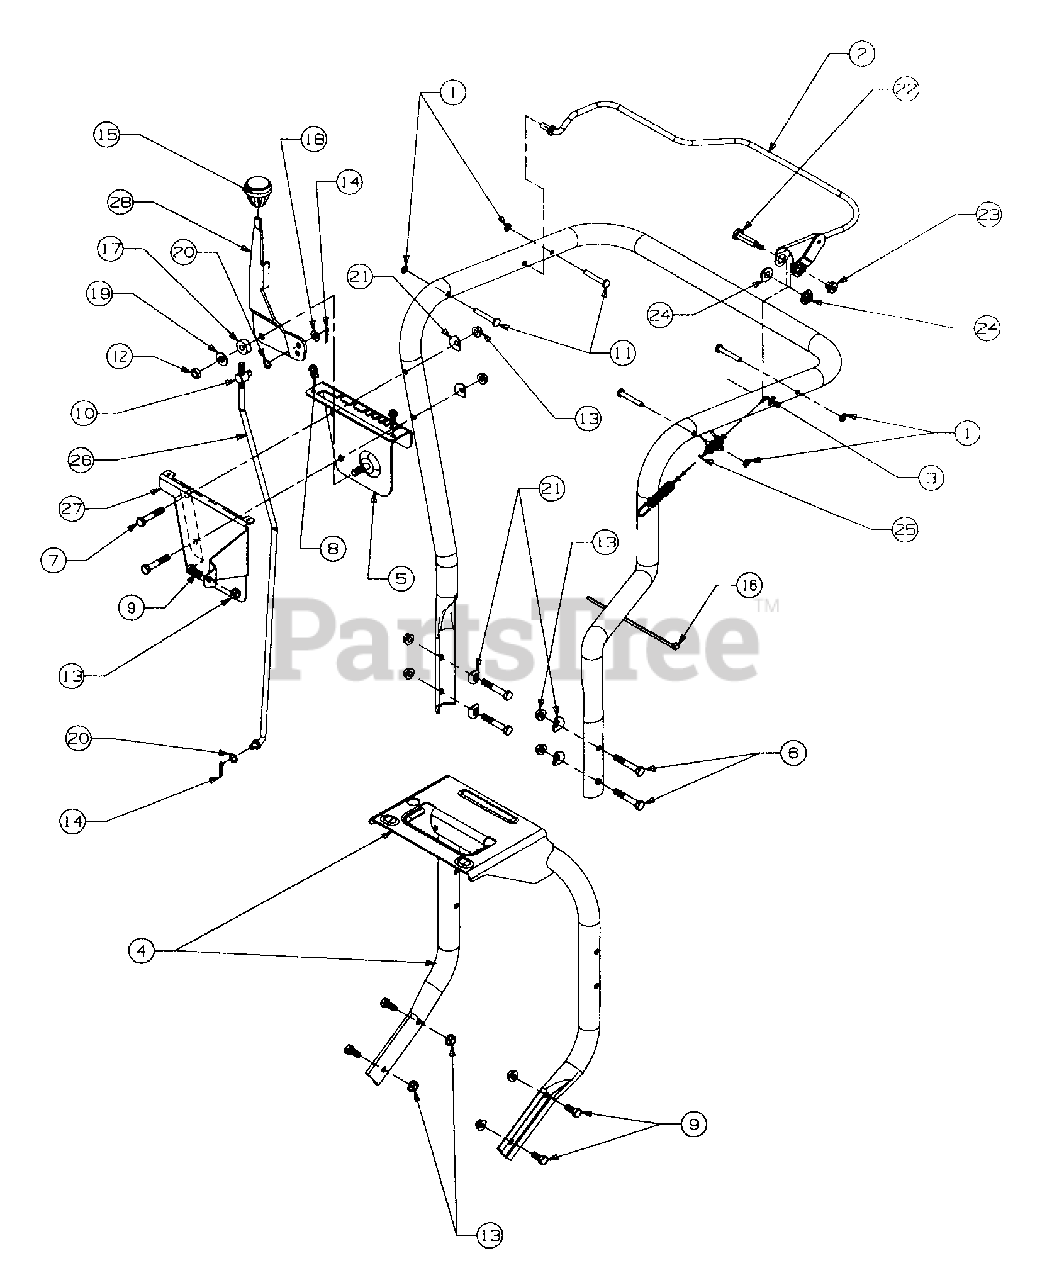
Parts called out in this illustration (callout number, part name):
7	SCREW - HEX
10	FERRULE
11	PIN - STUD
12	NUT - HEX LOCK
13	NUT - HEX LOCK
14	PIN - COTTER
15	KNOB - SHIFT
17	WASHER - RUBBER
18	WASHER - FLAT
19	WASHER - FLAT
20	WASHER - SPRING
21	WASHER - SADDLE
22	SCREW - SHOULDER
23	NUT - SHOULDER
24	BEARING - FLANGE PLASTIC
25	CABLE - CLUTCH
